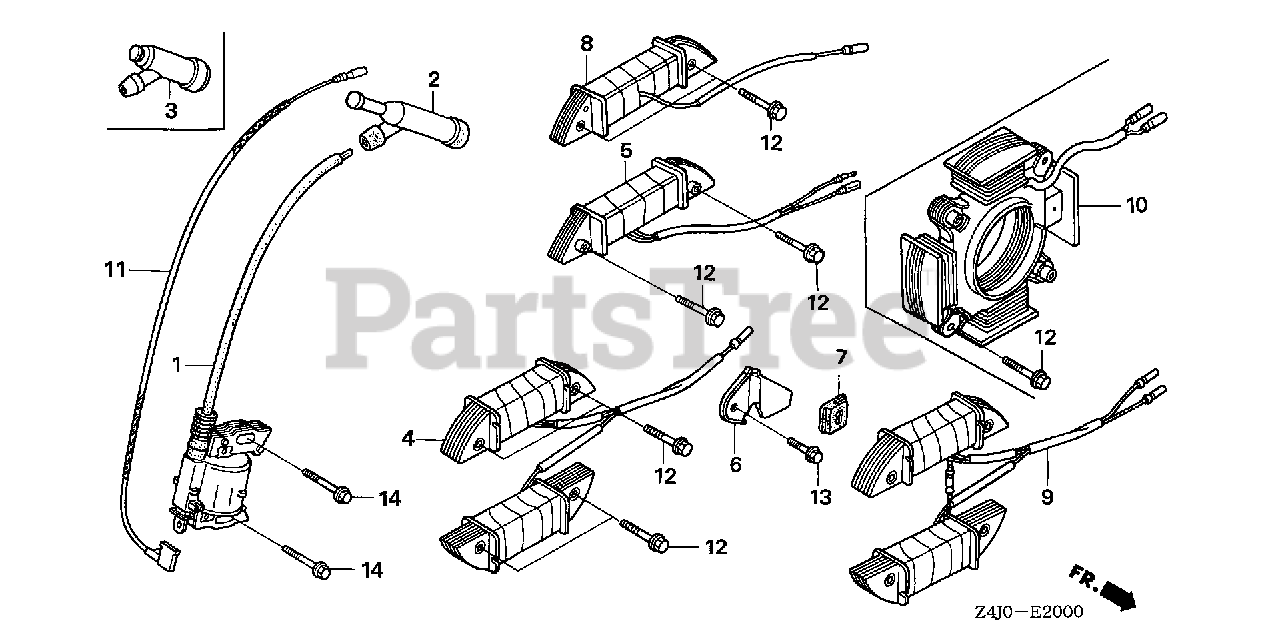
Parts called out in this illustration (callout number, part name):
1	COIL ASSY., IGNITION
2	CAP ASSY., NOISE SUPPRESSOR (NICHIWA Y-EZ RTFM256)
11	WIRE, STOP SWITCH (370MM)
14	BOLT, FLANGE (6X25) (CT200)
